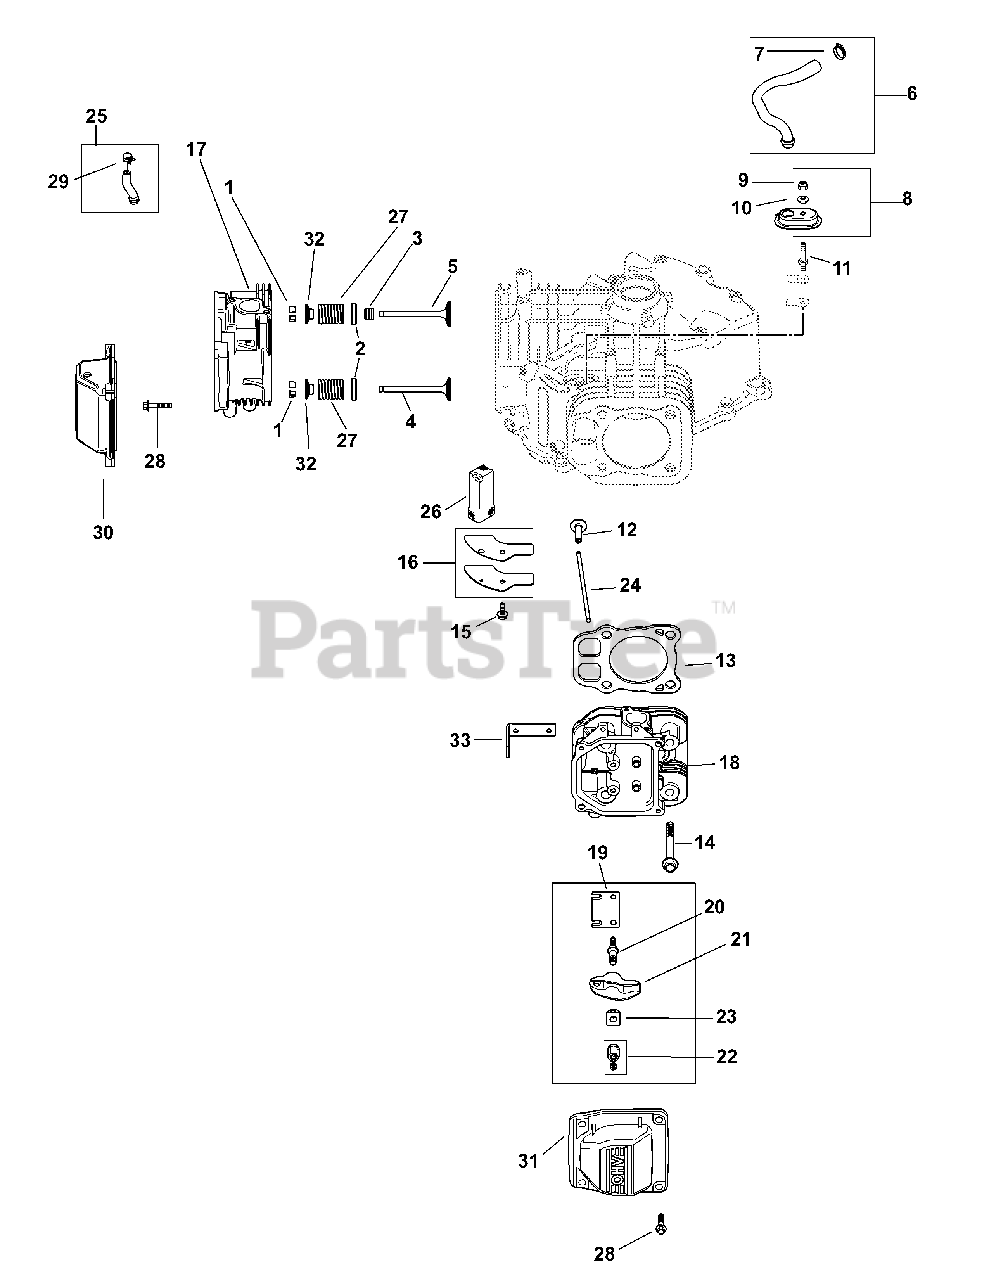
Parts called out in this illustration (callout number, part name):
1	Retainer Kit
2	Spring Retainer
3	Valve Stem Seal
4	Exhaust Valve
5	Intake Valve
6	Breather Hose Kit (Inc. 7)
7	Hose Clamp, 1/2
8	Breather Housing Kit (Inc. 9 & 10)
9	Lock Nut, M5 x .8
10	Sealing Washer
11	Breather Cover Stud
13	Cylinder Head Gasket Kit
14	Flg. Screw, M10 x 1.5 x 90
15	Flg. Thd. Frm. Screw, M6 x 1.0 x 16
16	Breather Cvr Kit (Inc. KH-32-041-S)
17	#1 Cylinder Head Assembly Kit
18	#2 Cylinder Head Assembly Kit
22	Hex Nut Assembly (Incl. set screw)
23	Rocker Arm Pivot
25	Fuel Pump Hose Kit w/Clamp
26	Breather Filter
27	Valve Spring
28	Screw, Pan Head
30	Rocker Stamped Steel Cover
31	Rocker Stamped Steel Cover
32	Valve Spring Cap
33	Lifting Strap
